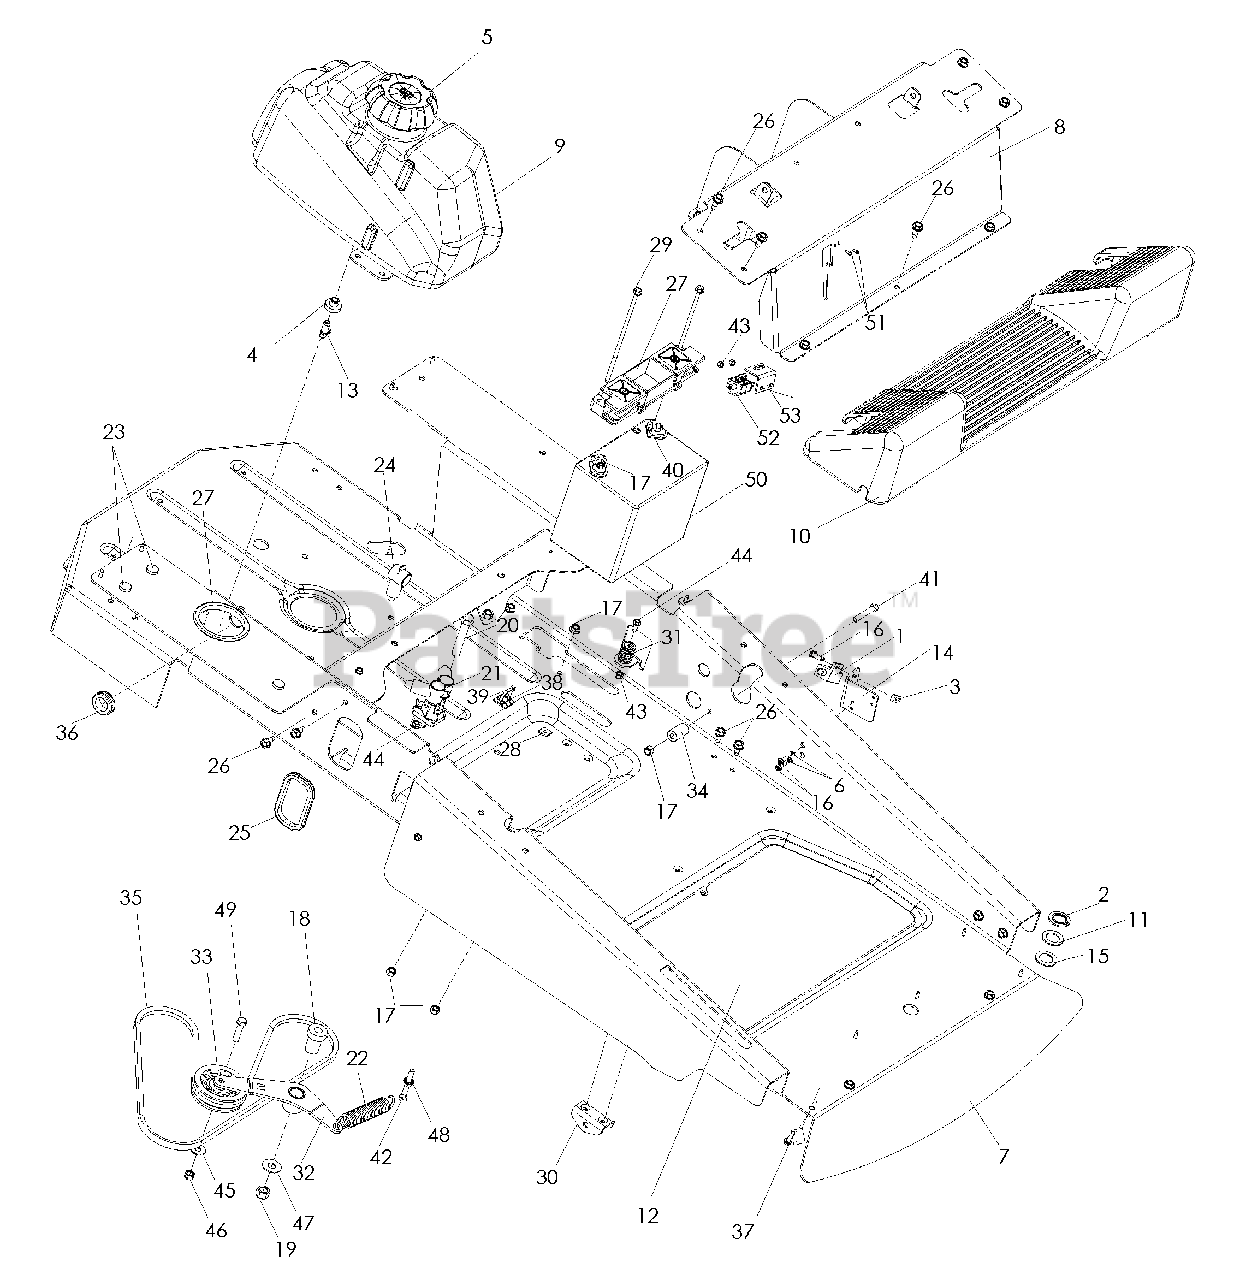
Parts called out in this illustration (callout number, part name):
1	SWITCH-INTERLOCK
2	RING-RETAINING EXT, 7/8
3	SCREW PLATE, #10-24
4	GROMMET, RUBBER
5	FUEL CAP, ANTISPLASH
6	LOCKWASHER, 3/16
7	CHASSIS W/DECALS
8	CONSOLE W/DECALS
11	WASHER, 7/8, WAVE
12	SLIP, MATTING
13	STEM, FUEL TANK
14	SWITCH BRACKET
16	SCREW, #10-24 x 5/8
17	NUT, 5/16-18, NYLOC
18	SPINDLE-IDLER
19	NUT,1/2-13, NYLOC
20	HCS,1/2-13 x 2 3/4
23	GROMMET, BUMPER
24	INSULATOR-BATTERY
26	BOLT, 5/16-18 x 3/4 THD FRM
27	BATTERY HOLD DOWN
28	NUT, 1/4, PUSH NYLON
29	BOLT, 1/4 x 71/2, SPEC
30	BRACKET, DECK HANGER
31	SPRING, RETURN
32	PUMP IDLER ARM
33	PULLEY, IDLER
34	MOTION LIMITER
36	GROMMET, FUEL LINE
37	SCRW, #10-12 x 1 1/2 WSH HD
38	MOUNTING BLOCK, TIE
39	TIE-PLASTIC
40	HCS, 5/16-18 x 3/4
41	HCS, 5/16-18 x 2
42	HCS, 5/16-18 x 2 1/4
43	NUT, 1/4-20, NYLOC
44	SCREW, 1/4-20 x 5/8 SELF TAP
45	WASHER, 3/8
46	NUT, 3/8-16, CENTERLOCK
47	WASHER,1/2
48	NUT, 5/16-18, WHIZLK
49	HCS, 3/8-16 x 1 1/2
50	BATTERY, DRY
51	HCS, 1/4 x1/2
52	SWITCH, BRAKE
53	BRACKET, SWITCH
